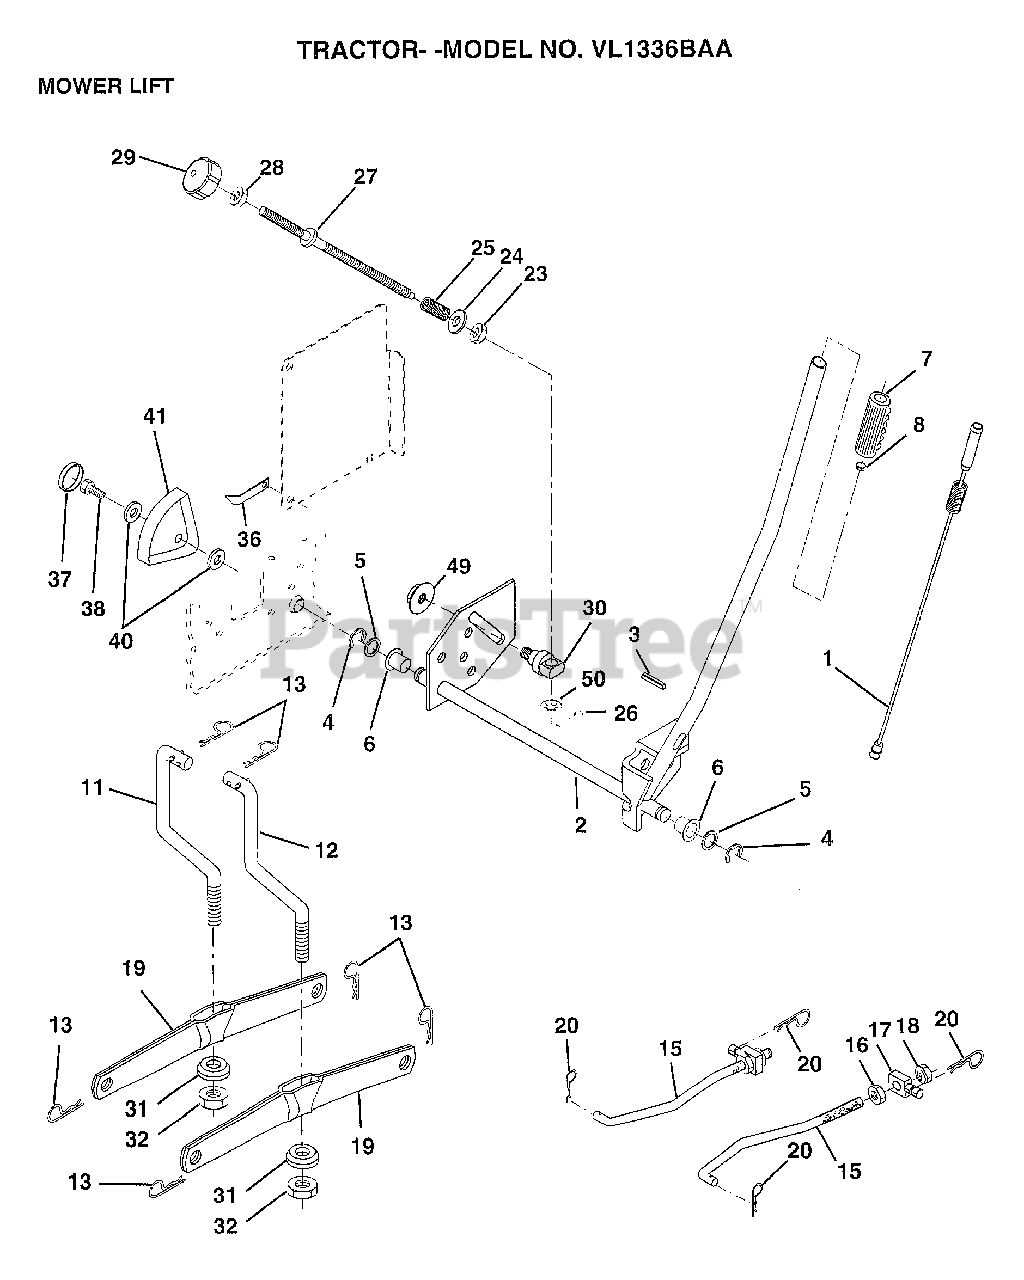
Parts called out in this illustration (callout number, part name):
1	WIRE ASM W.SPRING
2	"SHAFT ASM LIFT,RH"
3	PIN-GROOVE LT
5	WASHER
6	NYLON BEARING
7	GRIP
11	LINK.LIFT.LH.CRD
12	LINK.LIFT.RH.CRD
15	LINK.FRONT
16	NUT
17	TRUNION
18	NUT LTV
19	ARM SUSP REAR
20	RETAINER SPRING
23	NUT T
24	WASHER
25	SPRING T
28	NUT
29	KNOB INF 3/8-16
30	TRUNNION
31	BEARING PVT LH
32	NUT.CROWNLOCK.3/8
36	POINTER-INDICAT
37	"PLUG,HOLE"
38	SCREW
40	WASHER
41	HEIGHT INDICATOR
49	NUT.HXFLG.LOCK.
50	NUT PUSH M
